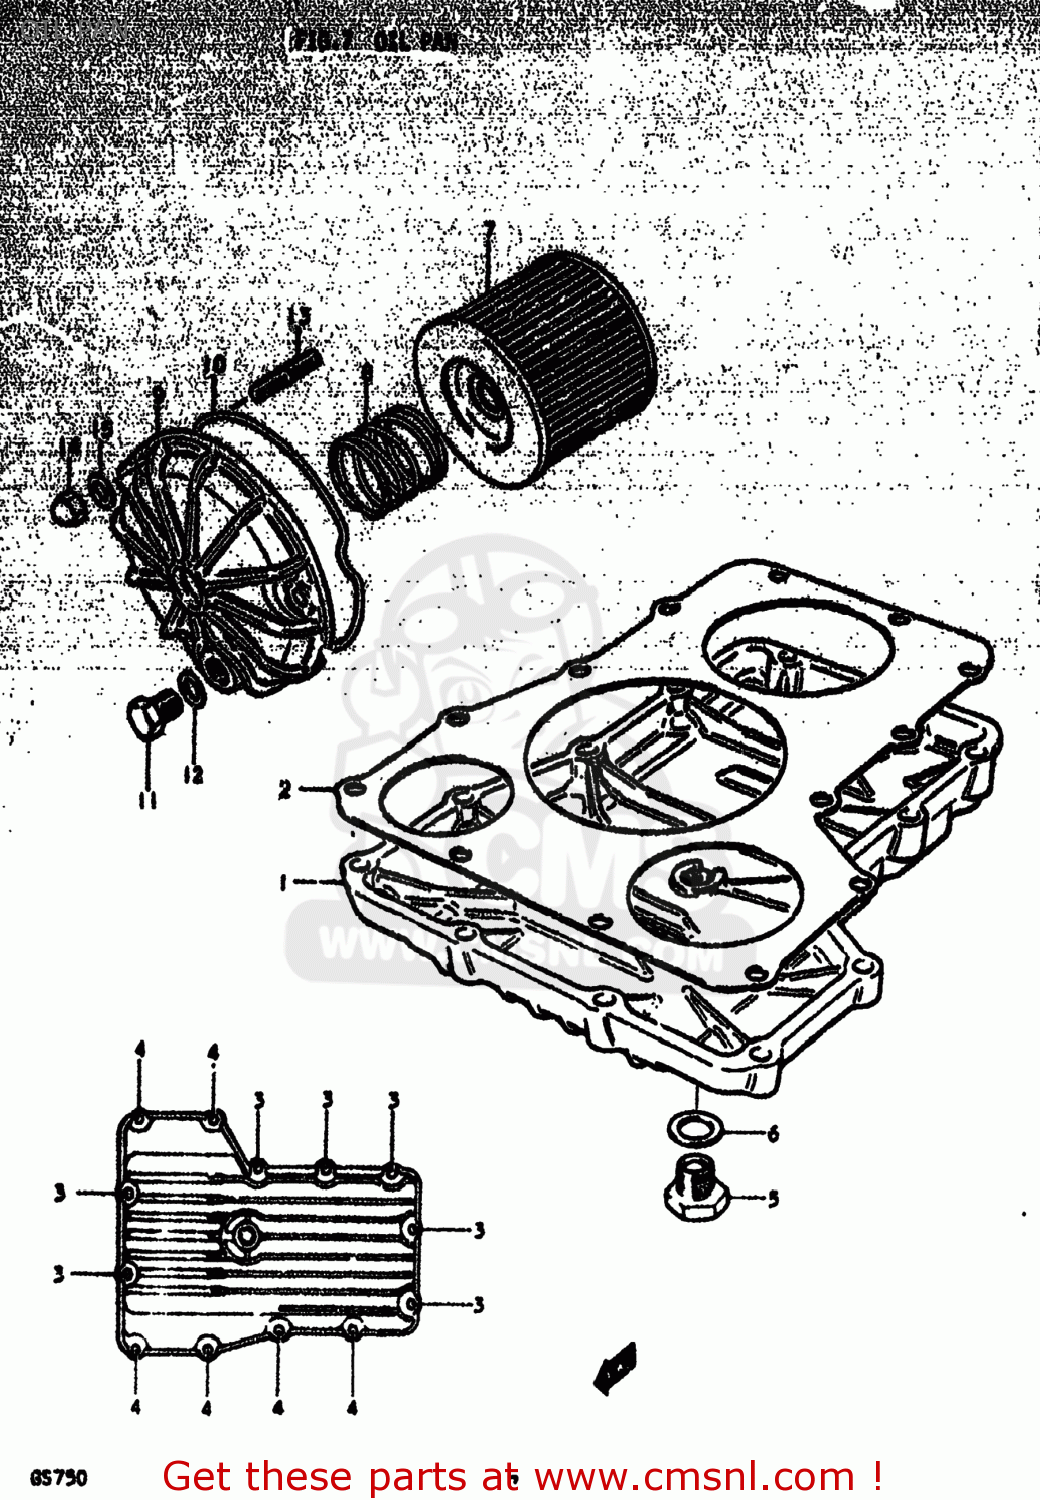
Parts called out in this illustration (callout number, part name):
1	PAN,OIL
2	GASKET,OIL PAN (MCA)
3	BOLT
4	BOLT
5	PLUG
6	GASKET(14X19.2X2) (NAS)
7	FILTER ASSY,ENGINE OIL
8	SPRING
9	CAP,OIL FILTER
10	O RING,OIL FILTER CHAMBER CAP
11	PLUG
12	GASKET(10X14X3.6) (NAS)
13	STUD 6X20
14	NUT
15	WASHER
